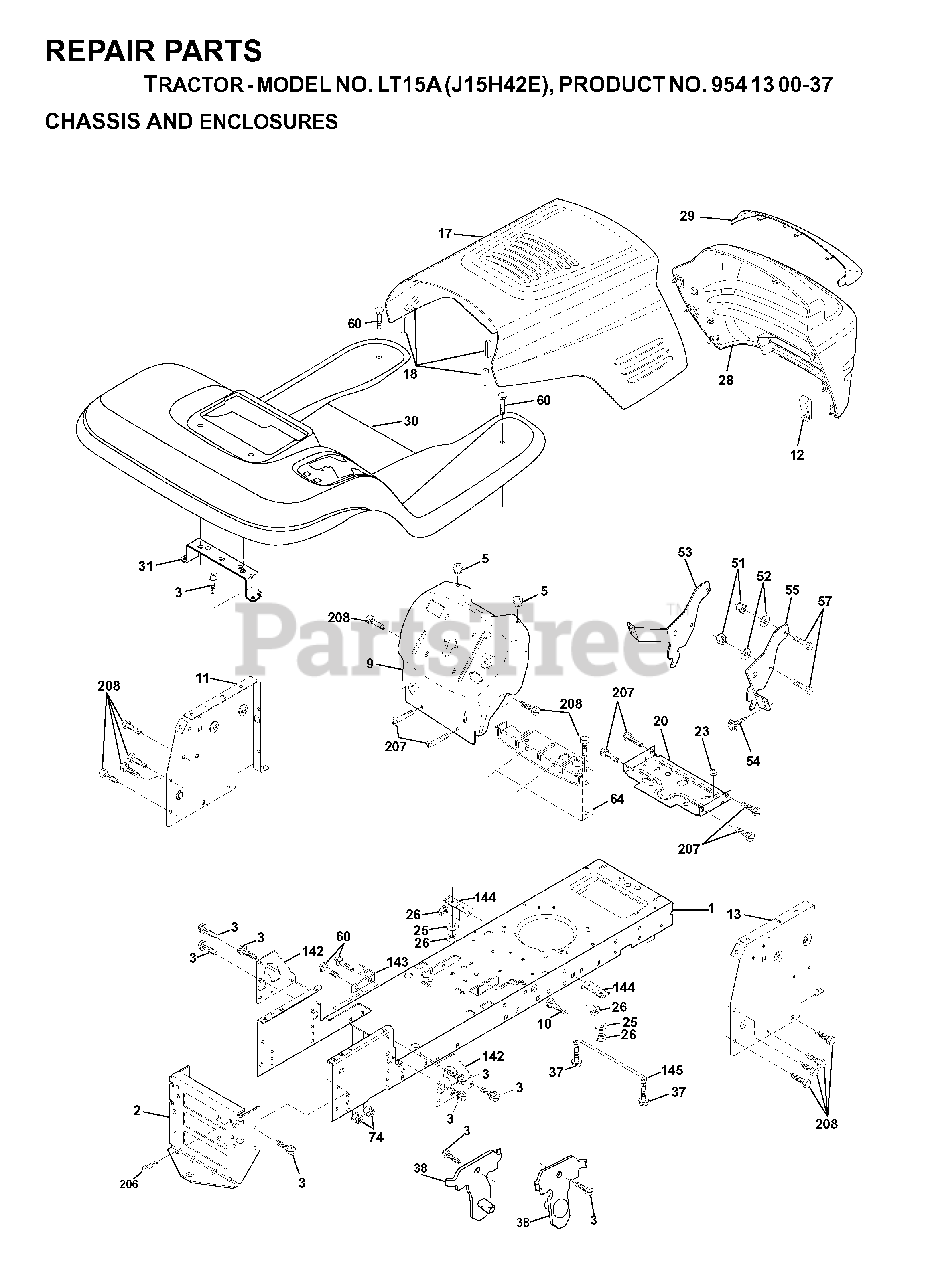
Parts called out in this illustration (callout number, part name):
2	DRAWBAR
3	SCREW 3/8-16X3/4
5	BUMPER.RUBBER.HOOD
10	BOLT D
11	PANEL DASH LH
13	PANEL DASH
18	BUMPER HOOD T
20	PLATE MTG
23	GROMMET T
25	WASHER
26	NUT
38	BRACKET
51	LOCKNUT
57	BOLT
64	DASH LOWER
74	LOCKNUT
140	BRACKET SUSPENSION FRONT
142	PLATE
143	BRACKET, SWAY BAR
144	BRACKET FOOTREST
145	ROD PIVOT CHASSIS/HOOD
206	SHOULDER BOLT 5/16-18TT
207	SCREW, 5/16-18 X 1/2
208	SCREW 3/8-16X1/2
